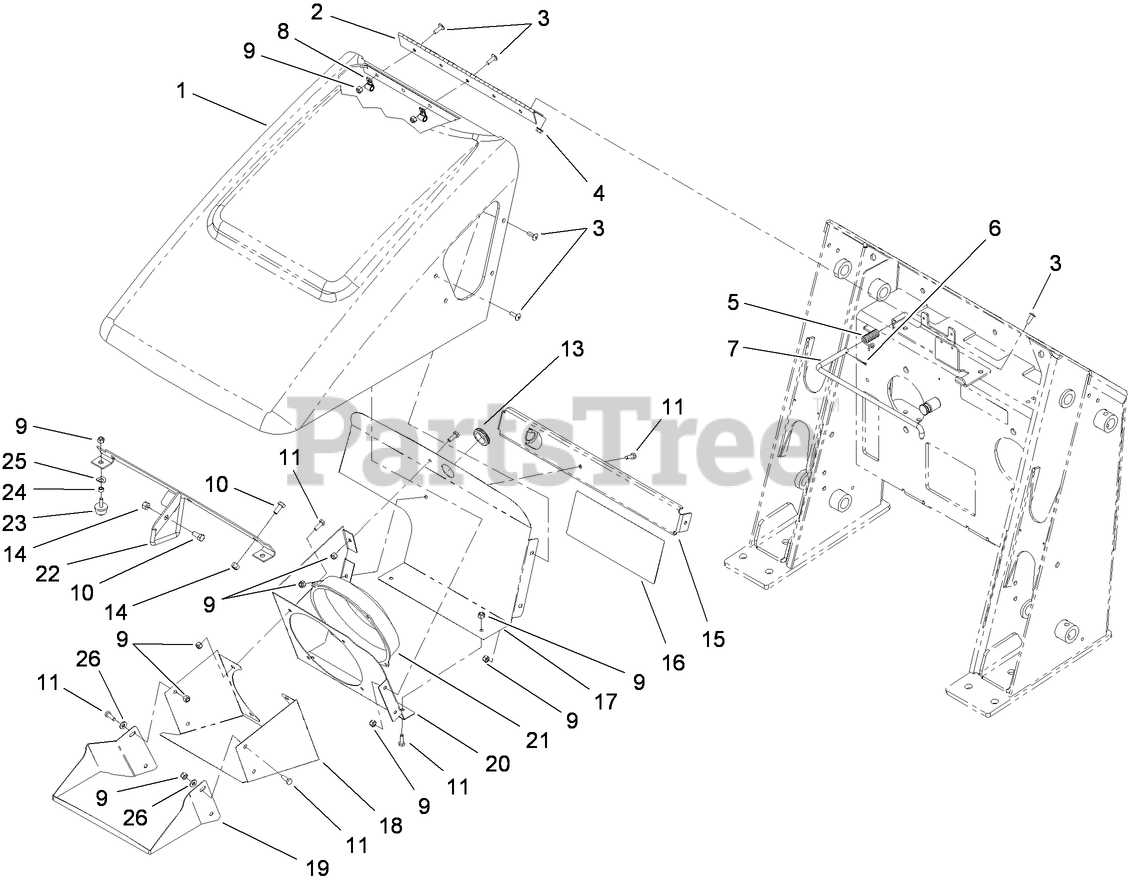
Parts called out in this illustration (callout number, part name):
1	HOOD ASM
2	HINGE-HOOD
3	SCREW-HEAD, TRUSS
4	NUT-HF
5	Spring-Torsion
6	PIN-COTTER
7	Rod-Support, Hood
8	CLAMP
9	NUT-LOCK, NI
10	SCREW-HH
11	SCREW-HH
13	GROMMET
14	NUT-LOCK, NI
15	BRACKET-SUPPORT, HOOD
16	DECAL-SERVICE
17	BRACKET-FAN, BACK
18	SHROUD-FAN
19	SHROUD-FAN, FRONT
20	BRACKET-FAN, BACK
22	ROD LATCH ASM
23	BUMPER
24	SPACER
25	WASHER-SPRING
26	WASHER-FLAT
